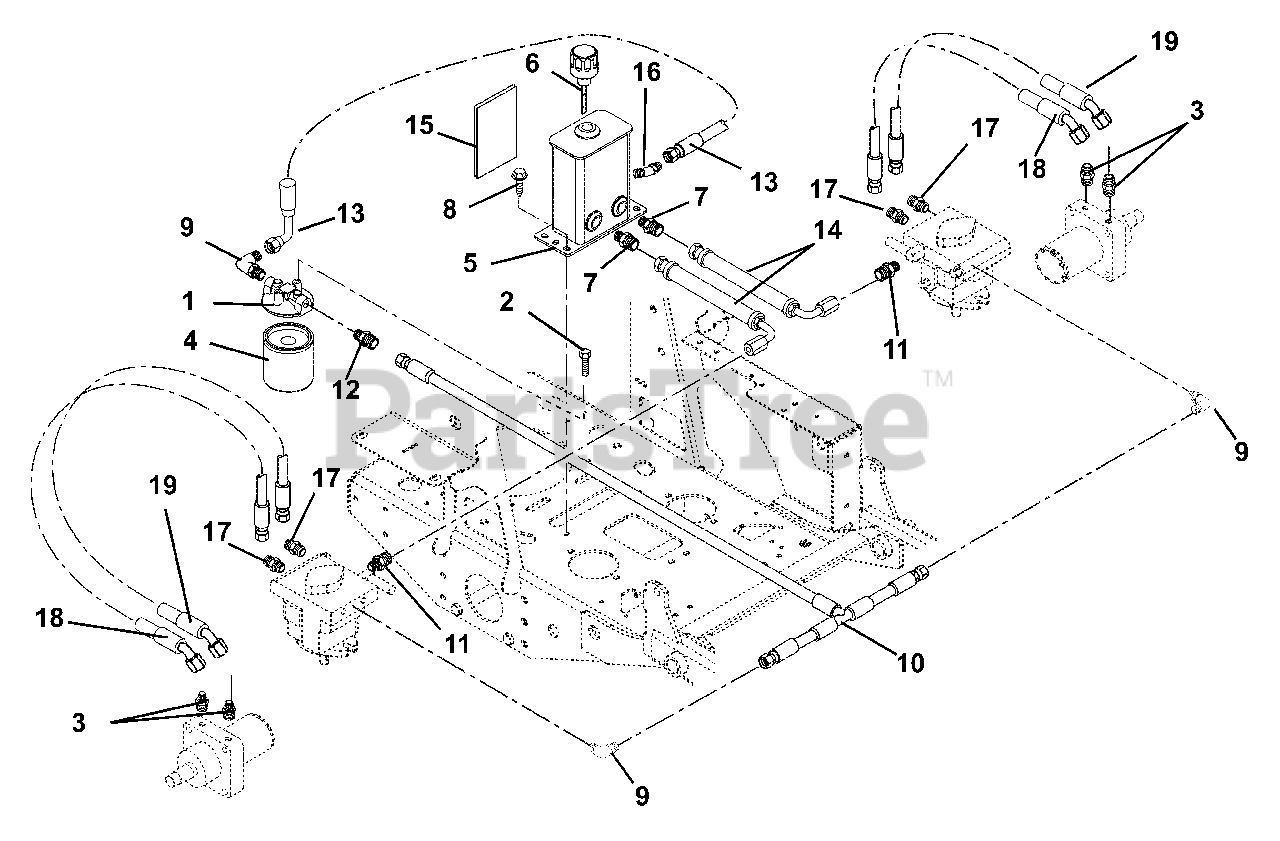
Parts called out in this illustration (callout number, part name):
1	HEAD, FILTER
2	BLT-HEX .25-20X.50 GR5 EPOXY
3	FTG, HYD STR M10O-M8F
4	ELEMENT, FILTER BE-40-0
5	WMT, HYDRAULIC TANK
6	BREATHER, DIPSTICK
7	FTG, HYD STR M8O-M4F
8	@SCR-TAP .38-16X.50 HWH TR YWZ
9	FITTING, HYD (6 C5OLO)
10	HOSE, TEE ASSM .38
11	FITTING, HYD (4-6 F5OLO)
12	FITTING, HYD (6 F5OLO)
13	HOSE, HYD .38-9-0K F6F0-F6F9
14	HOSE, HYD .25-3-0K F4F0-F4F9
15	SHEILD, HEAT 5.50X4.50
16	FTG, HYD 45DEG M6F-M8O
17	ADPTR,FACE SEAL 8X8 1/2 O-RING
18	HOSE,HYD .50-11-3K F8O0-F8O4
19	HOSE,HYD .50-12-3K F8O0-F8O4
